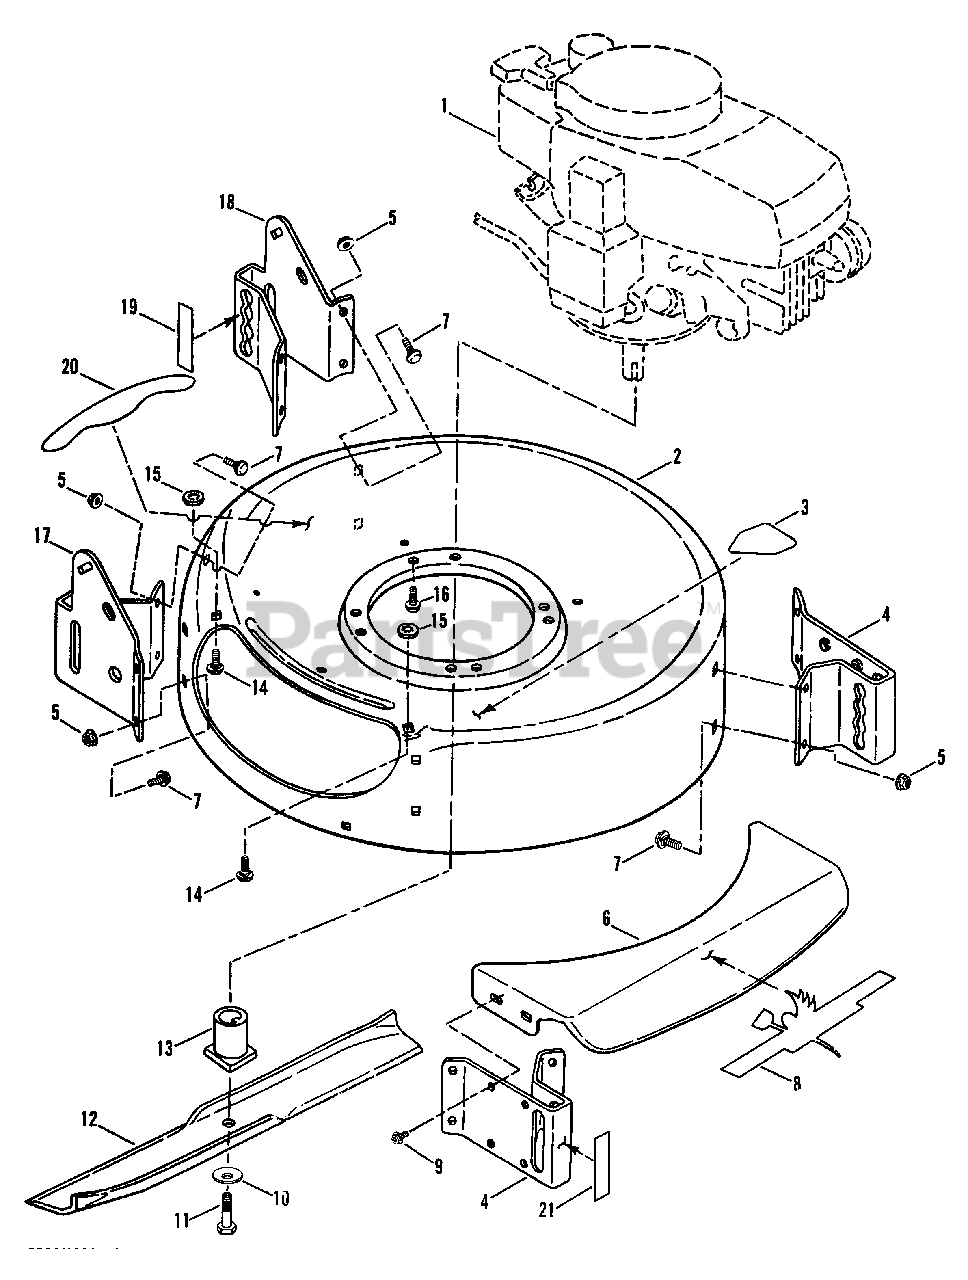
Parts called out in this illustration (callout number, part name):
2	DECK, 20" Cutting
3	DECAL, DANGER (Keep Hands & Feet Away)
4	BRACKET, Front Wheels
5	NUT, 5/16-18 Hex Flange Lock, Grade 5
6	PLATE, Deck Front
7	BOLT, 5/16-18 x 1/2 Short Neck Carriage, Grade 5
8	DECAL, Lady Garden
9	SCREW, #10-24 x 1/2" Hex Washer Self-Tap (Torx)
10	WASHER, Cone
11	SCREW, 3/8-24 x 1 3/4" Hex Head Cap, Grade 5
12	BLADE, Mulching
13	HUB, Blade
14	BOLT, 5/16-18 x 3/4 Short Neck Carriage, Grade 5
15	RETAINER, 5/16 Bolt
16	SCREW, 3/8-16 x 1" Hex Washer Head, Self-Tapping
17	BRACKET, Rear Wheel (Right Side)
18	BRACKET, Rear Wheel (Left Side)
19	DECAL, Height Adjustment
20	DECAL, WARNING, Chute & Deflector
